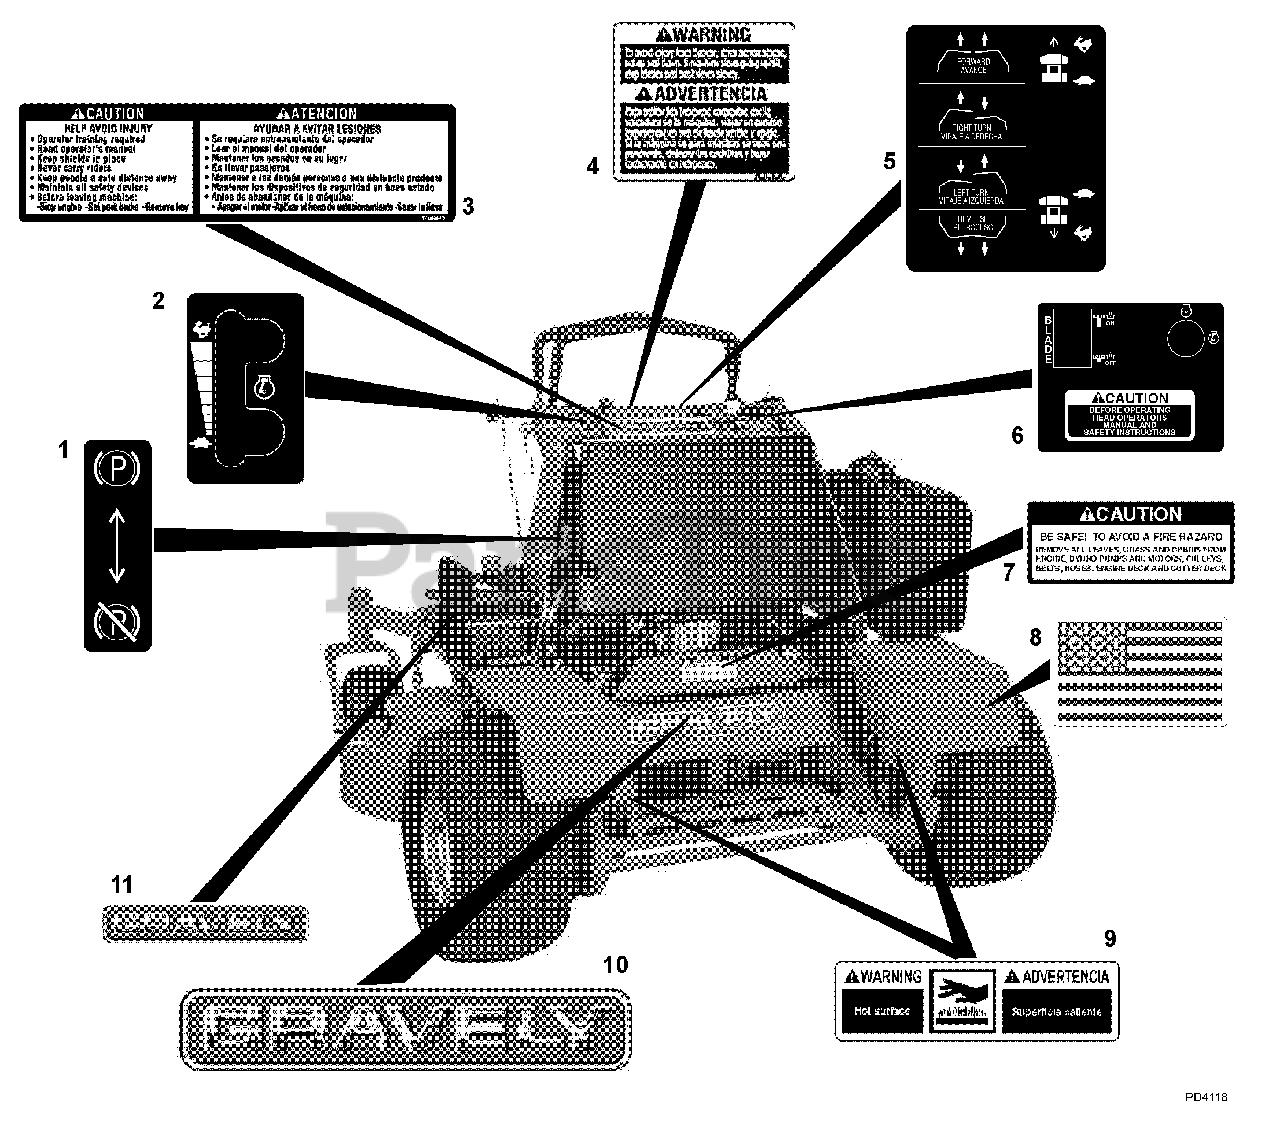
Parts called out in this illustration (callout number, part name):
1	Decal, Park Brake
2	Decal, Throttle
3	Decal, General Caution
4	Decal, Danger - Avoid Tipover
5	Decal, Directional Control
6	Decal, PTO/Ignition
7	Decal, Caution - Fire Hazard
8	Decal, American Flag
9	Decal, Warning, Hot Surface
10	Decal, 15" Gravely Logo
11	Decal, Gravely Logo
